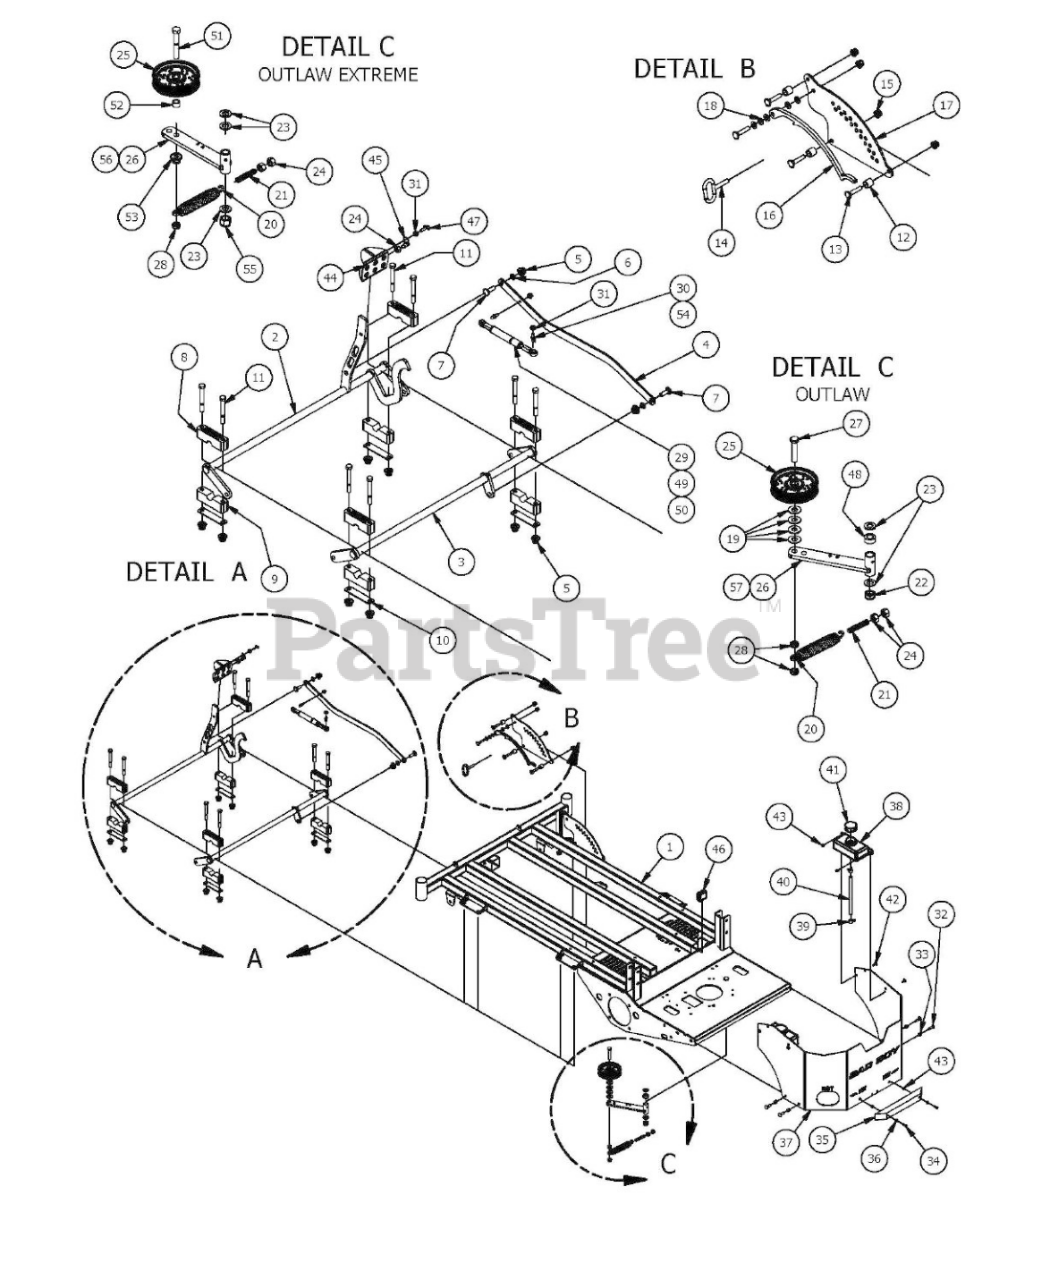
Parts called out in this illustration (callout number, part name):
1	2017 Standard/Extreme Outlaw Frame
2	2015 Outlaw Act Bar Assembly (Front)
3	2015 Outlaw Act Bar Assembly (Rear)
4	Outlaw Deck Linkage Rod
5	1/2-13 Nylon Flange Nut
6	Bushing- SF-1620-4
7	1/2 x 1-1/2 Carriage Bolt
8	Two Piece Pillow Block (Male)
9	Two Piece Pillow Block (Female)
10	Two Piece Pillow Block Strap
11	1/2" x 4" Bolt (Grade 8)
12	Spacer 3/4 OD x 1/2 ID x 314 Length
13	3/8 x 1 3/4 Carriage Bolt
14	Deck height lever pin
15	3/8" Nylock Flange Nut
16	Outlaw Deck Lever Lock
17	Outlaw Height Indicator Plate (Outer)
18	.390 x .750 x .062 Nylon Washer
19	1/2" Brass Washer (Base Only)
20	2009 Deck/Pump Idler Spring
21	All Thread-Pump Idler Tensioner
22	5/8" Nylock (1/2 Jam) (Base Only)
23	.630 ID Plastic Washer
24	1/2" Hex Nut
25	4 3/4 Idler Pulley - ABFI-76
26	Deck Idler
27	1/2" x 3" Hex Bolt (Base Only)
28	1/2" Nylock Nut (1/2 Jam)
29	200 lb Gas Spring- 54" Deck outlaw
30	10mm Damper Ball Stud-Steering
31	5/16" Flange Nut
32	3/8" x 1 1/4" Carriage Bolt
33	3/8 Nylock Nut
34	1/4-20 x 1-1/4 GR 5 Hex Bolt
35	14" Rubber Bumper
36	1/4" Flat Washer
37	Outlaw Rear Plate
38	Expansion Tank Outlaw
39	5/8 Wire Clamp-Outlaw Only
40	5/8 Braided Hose
41	Hydraulic Tank Cap
42	1/4" x 3/4" Carriage Bolt
43	1/4-20 Nylon Insert flange Nut
44	Outlaw Deck Lift Pedal
46	2X2 Frame Plug
47	5/16-18 x1 Thumb Screw Zinc
48	5/8" x 1/" Collar W/One Set Screw
49	250 lb Gas Spring - 61" Deck Outlaw
50	300 lb Gas Spring - 72" Deck Outlaw
51	1/2 x 2-1/2 Hex Bolt (Extreme Only)
52	1/2" x 1/2 Spacer (Extreme Only)
53	1/2"-13 Nylon Flange Nut (Extreme Only)
54	13mm Damper Ball Stud for 72" Deck only
55	5/8 Std NC Nylock Nut (Extreme Only)
56	Pump Idler Assy - Outlaw Extreme Components:25,26,28,51,52,53
57	Pump Idler Assy - Base Outlaw Components:19,25,26,27,28
